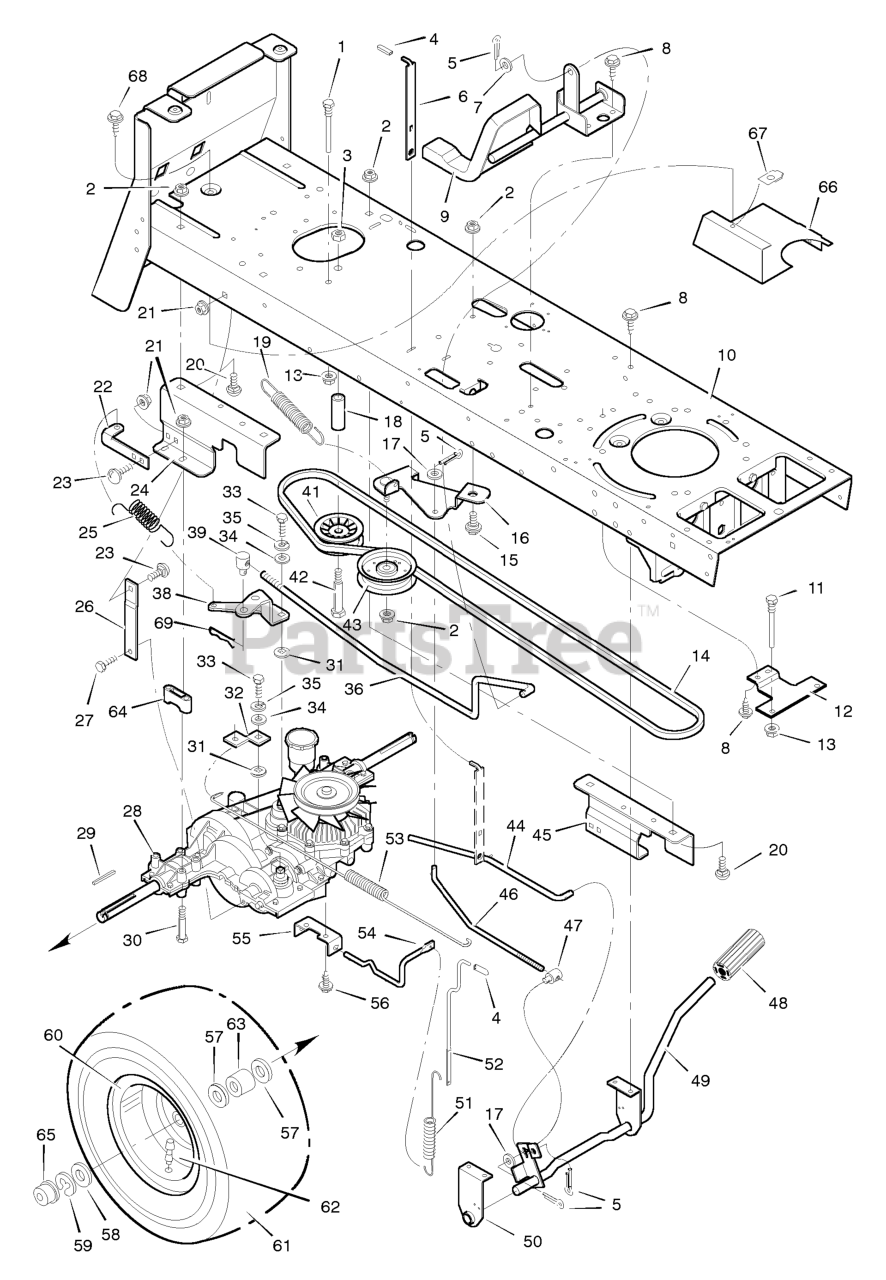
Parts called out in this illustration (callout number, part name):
1	Guide, Belt
2	Nut, Flange
3	Nut, Hex
5	Pin, Hair
6	Lever, Parking Brake
7	Washer
9	Pedal Assembly
10	Frame Assembly
11	Guide, Belt
12	Bracket, Belt Guide
13	Nut, Flange
15	Bolt, Shoulder
16	Bracket, Idler
17	Washer
18	Spacer
20	Bolt, Carriage
21	Nut, Flange
22	Bracket, Spring
23	Bolt, Carriage
24	Bracket, Right Transaxle
26	Bracket, Torque
28	Transaxle **
29	Key, Square
32	Yoke, Brake
35	Lockwasher
36	Rod, Control
38	Lever, Control
39	NUT, Adjusting, 1/2-13
41	Pulley, Idler
43	Pulley, Idler
44	Rod, Latch
45	Bracket, Left Transaxle
46	Rod, Clutch
47	Nut, Adjusting
48	Pedal
49	Lever Assembly, Pedal
50	Pedal Assembly
51	Spring, Extension
52	Rod, Dump Valve
53	Spring, Extension
54	Rod, Dump Valve
55	Bracket, Dump Valve
59	E- Ring
60	Wheel and Tire Assembly
61	Tire *
62	Valve Stem
63	Spacer, Wheel
64	Spacer, Transaxle
65	Hub Cap
66	Air Baffle, Hydro
67	Nut, Speed
68	Screw
69	Pin, Hair
